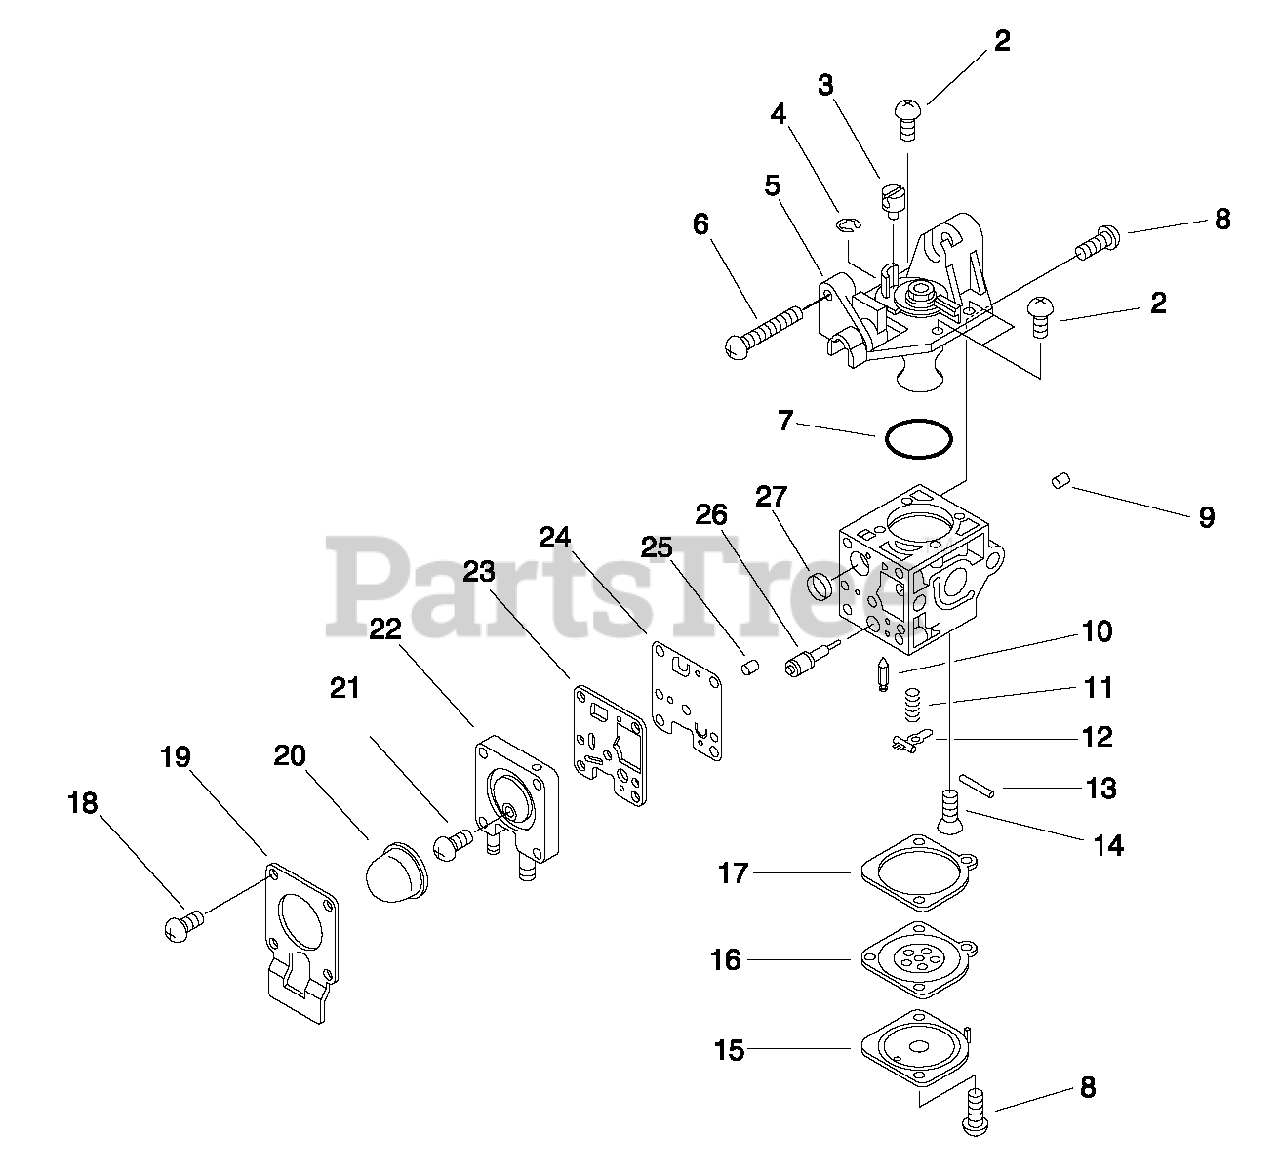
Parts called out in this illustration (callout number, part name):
1	CARBURETOR
4	RING, RETAINING
5	ROTOR COVER ASSY
6	SCREW, IDLE ADJUST
9	ROLLER, GUIDE
10	VALVE, INLET NEEDLE
11	SPRING, METERING LEVER
12	LEVER, METERING
13	PIN, METERING LEVER
14	SCREW, METERING LEVER PIN
15	COVER, METERING
16	DIAPHRAGM, METERING
17	GASKET, METERING
18	SCREW, RETAINER
19	RETAINER
20	BULB, PURGE
21	SCREW, PURGE BASE
22	PRIMER BASE ASSY
23	GASKET, PUMP
24	DIAPHRAGM, PUMP
25	CAP, LIMITER
26	NEEDLE - HIGH SPEED
27	STRAINER
